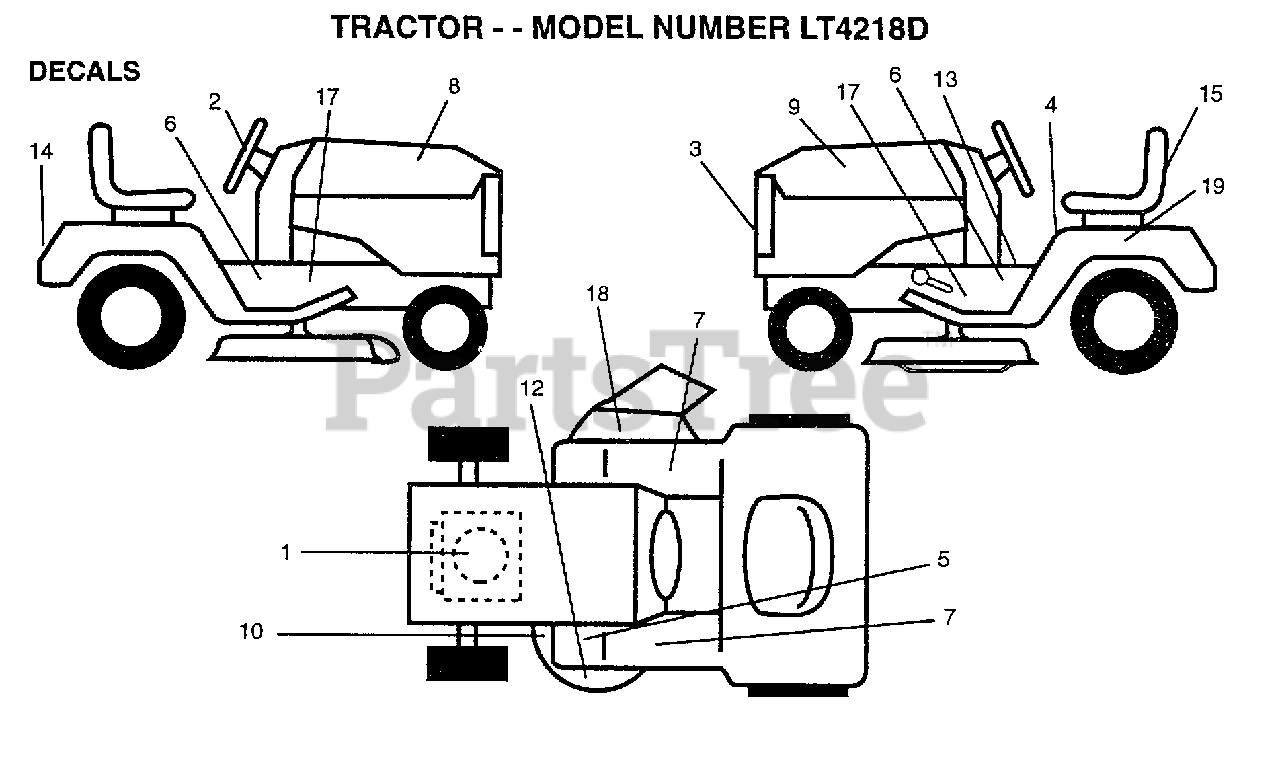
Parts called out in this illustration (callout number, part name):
1	DECAL B&S 18 HP TWIN IC
2	DECAL INST WHL
3	DECAL LOGO GRILLE
4	DECAL CAUT FEND
5	DECAL CLUT/BRAKE
6	DECAL CHASSIS KGR
7	FOOTREST PAD
8	DECAL.HD.RH.KGRO
9	DECAL.HD.LH.KGRO
10	DECAL
12	DECAL.DECK.KGRO.
13	DECAL.SADDLE.INST
14	DECAL.FEND.KGRO
17	DECAL.CHAS.KGRO
18	DECAL DANGER CT/F
19	DECAL.BTRY.DANGER
